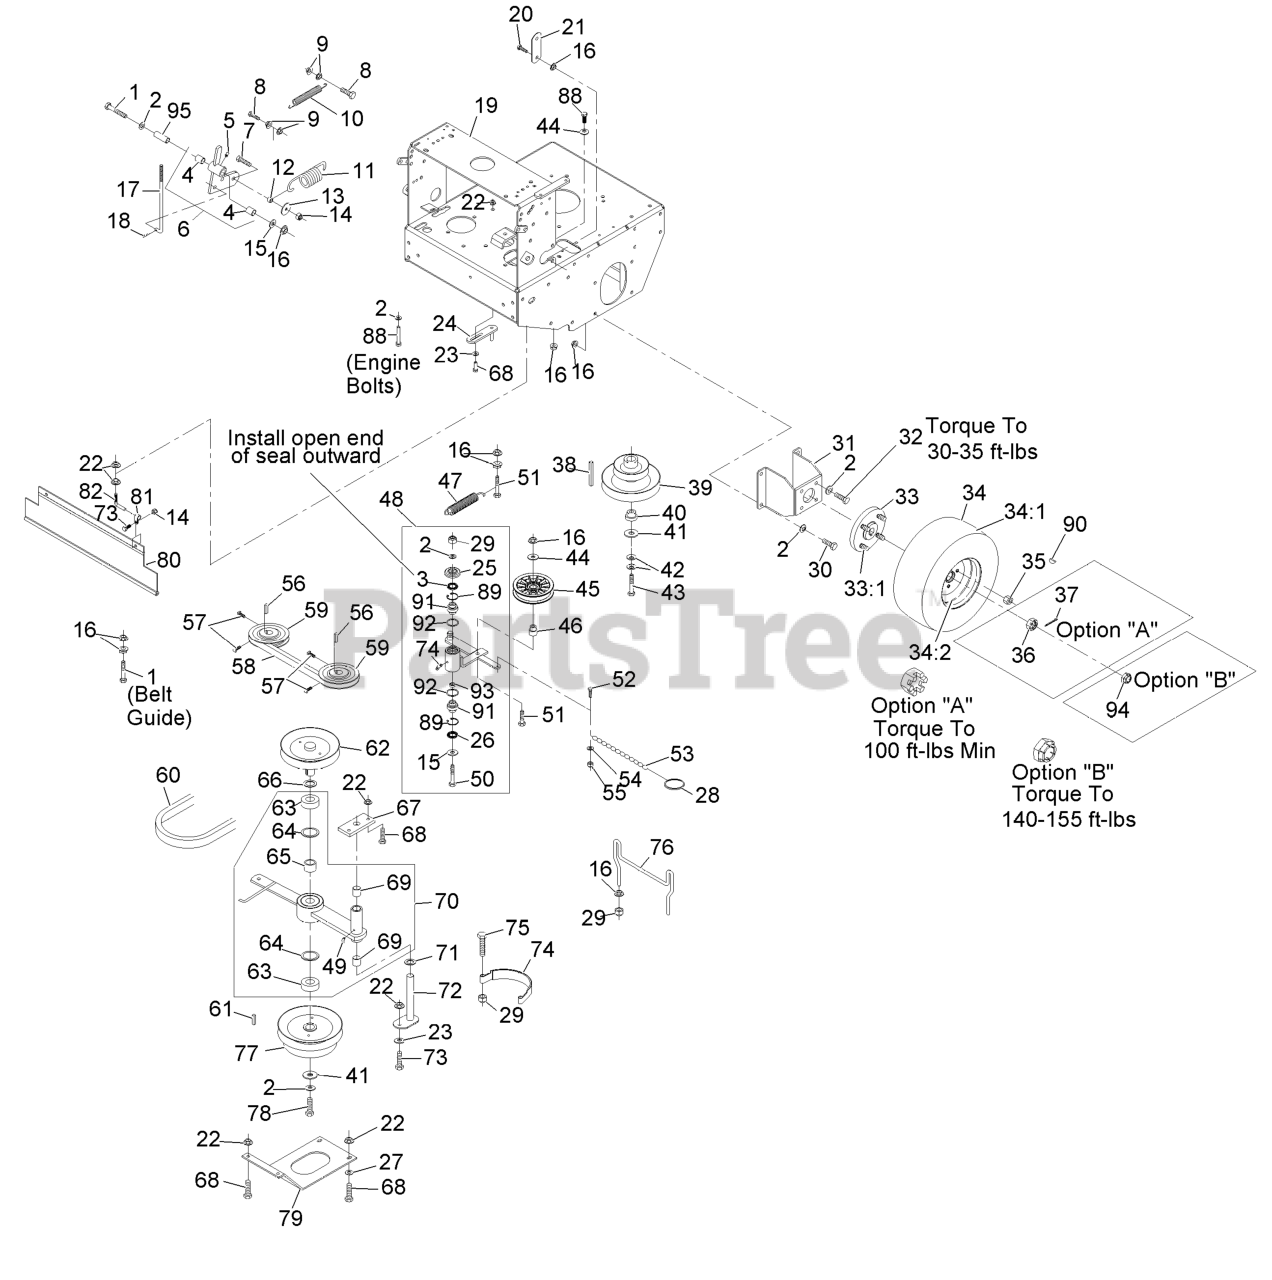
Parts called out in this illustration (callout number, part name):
1	SCREW-HH
2	WASHER-BELLEVILLE
3	SEAL-LIP, SINGLE
4	SLEEVE-BEARING
5	FITTING-GREASE
6	ASM,PIVOT W/BUSHINGS
7	SCREW-HH
8	SCREW-HH
10	SPRING,EXTENSION
11	SPRING,EXTENSION
12	SPACER,CLUTCH ANCHOR
14	NUT-LOCK, NI
15	WASHER-FLAT
16	NUT-HHF, WHIZ
17	LINKAGE,LOWER
18	PIN-COTTER
19	KIT,TTHP ENG DECK
20	SCREW-HH
21	ARM-LIFT, DECK
23	WASHER-SPRING
24	GUIDE-BELT
25	GUARD-TOP
26	SEAL-LIP, DOUBLE
27	WASHER-FLAT
28	RING-SPLIT
29	NUT-LOCK, NI
30	SCREW-HH
31	WLD,MOTOR MOUNT 36
32	SCREW-HH
33:1	STUD-WHEEL
34	WHEEL AND TIRE ASM
34:1	TIRE-TURFMASTER
34:2	RIM-WHEEL
35	NUT-LUG
36	NUT-HEX, SLOTTED
37	PIN-COTTER
38	KEY,MACH 1/4X1/4X2-5/8
39	SHEAVE, DRIVE
40	BUSHING,CLUTCH KEEPER
42	WASHER-SPRING
43	SCREW-HH
44	WASHER-FLAT
45	PULLEY-IDLER, FLAT
46	BUSHING-IDLER
48	KIT,PUMP IDLER ARM TTHP
49	FITTING-GREASE
50	SCREW-HH
51	SCREW-HH
52	SCREW-HSH
53	CHAIN-LINK, TWIST
54	WASHER-FLAT
55	NUT-LOCK, NI
57	SCREW-SET
58	BELT,COG A 50.55
59	SHEAVE ASM
60	BELT,B-38.0
62	SHEAVE, W/ SHAFT
63	BEARING,CLUTCH SHAFT
64	RING-SNAP
65	SPACER,CLUTCH BEARING
66	WASHER-SPACER
67	PLATE-CLUTCH PIVOT
68	SCREW-HH
69	SLEEVE,BEARING
70	ASM,CLUTCH ARM W/BEARING
71	WASHER-SPACER
72	WLD,PIN PIVOT
73	SCREW-HH
74	BAND,BRAKE BLADE
75	SCREW-HH
76	GUIDE,BELT (PLTD)
77	SHEAVE,6.13 W/HUB
78	SCRW,CAP HH
79	PLATE-GUARD
80	SHIELD-DRAG
81	CLIP-LOOM
82	MOUNT,DRAG SHIELD
88	SCREW-HH
89	RING-SNAP
90	KEY-WOODRUFF
91	BEARING-SPHERICAL
94	NUT-LOCK
95	BUSHING
